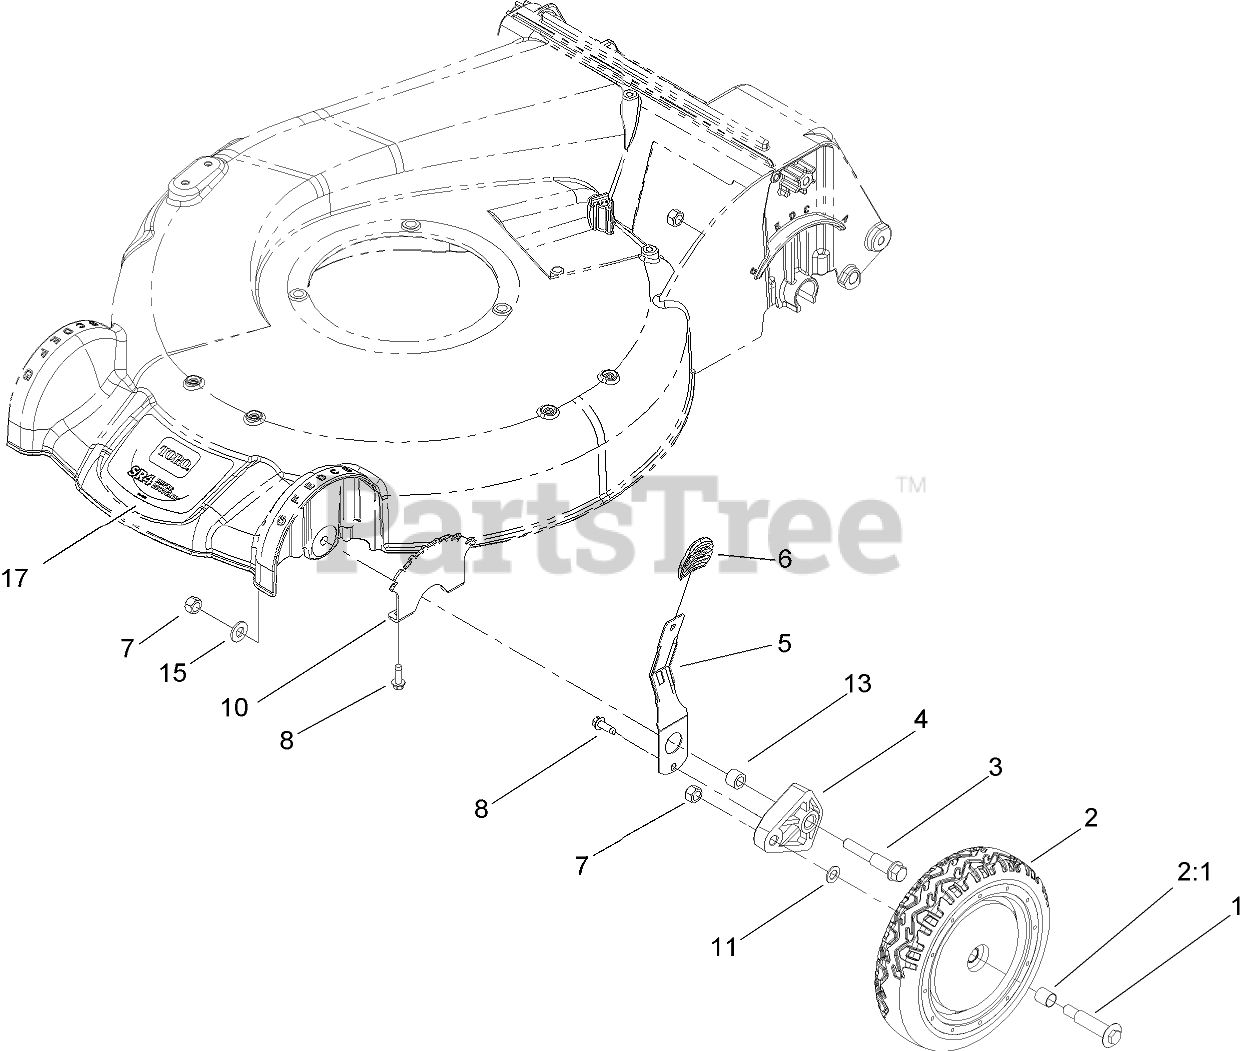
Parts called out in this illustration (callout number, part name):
1	BOLT-SHOULDER
2	8 INCH WHEEL ASM
2:1	BUSHING
3	SCREW-SHOULDER, HOC
4	ARM-PIVOT
5	ARM-SPRING
6	Knob-Lever, HOC
8	SCREW-HWHTF
10	PLATE-HOC
11	WASHER
13	SPACER-WHEEL
15	WASHER-FLAT
